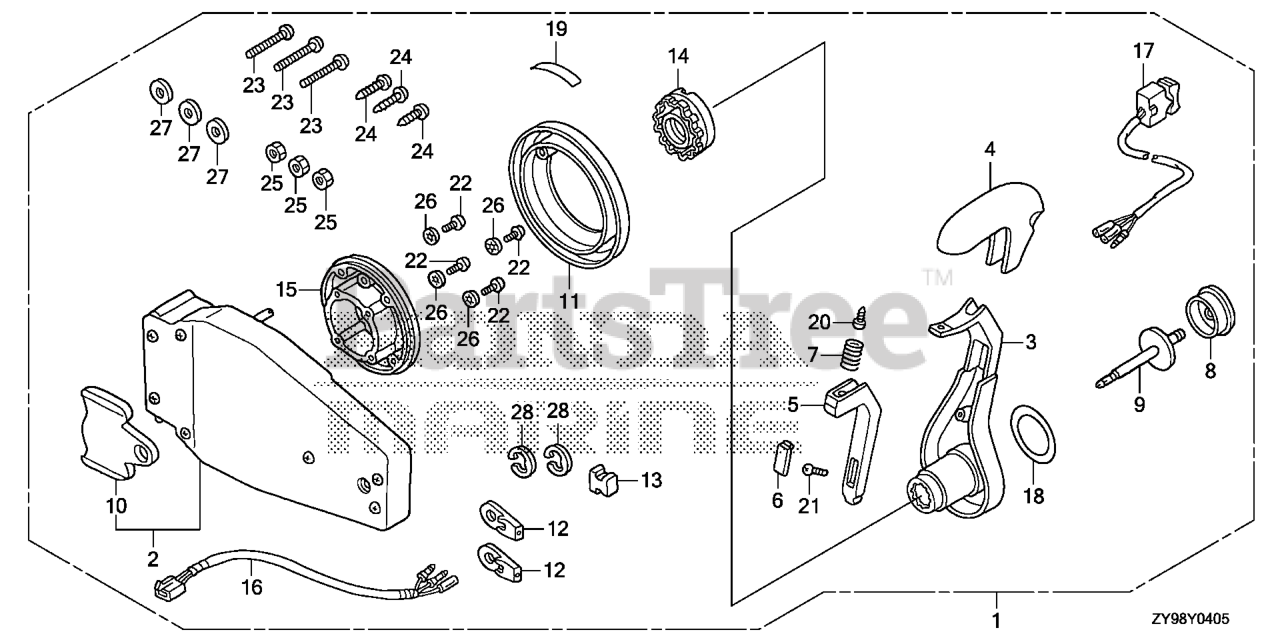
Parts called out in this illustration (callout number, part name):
1	BOX KIT, REMOTE CONTROL (FLUSH MOUNT)(L)
2	HOUSING ASSY., L. (INNER) (FLUSH MOUNT)
3	HANDLE, REMOTE CONTROL
4	COVER, GRIP
5	ARM, NEUTRAL LOCK
6	COVER, LOCK ARM
7	SPRING, NEUTRAL LOCK ARM
8	BUTTON, THROTTLE
9	SHAFT, THROTTLE BUTTON
10	PLATE, DWELL
11	COVER ASSY.
12	TERMINAL, CABLE
13	SPACER, CABLE CLAMP
14	HOLDER, NEUTRAL LOCK
15	BASE
16	SUB-HARNESS ASSY., POWER TRIM-TILT (C)
17	SWITCH ASSY., POWER TRIM-TILT (C)
18	MARK, HANDLE FLUSH MOUNT
19	MARK, FLUSH MOUNT
20	SCREW, PAN (5X16)
21	SCREW, TRUSS (4X12)
22	SCREW, PAN (5X30)
23	SCREW, PAN (6X35)
24	SCREW, TAPPING (6X30)
25	NUT, HEX. (6MM)
26	WASHER, LOCK (5MM)
27	WASHER, PLAIN (6MM)
28	E-RING (6MM)
